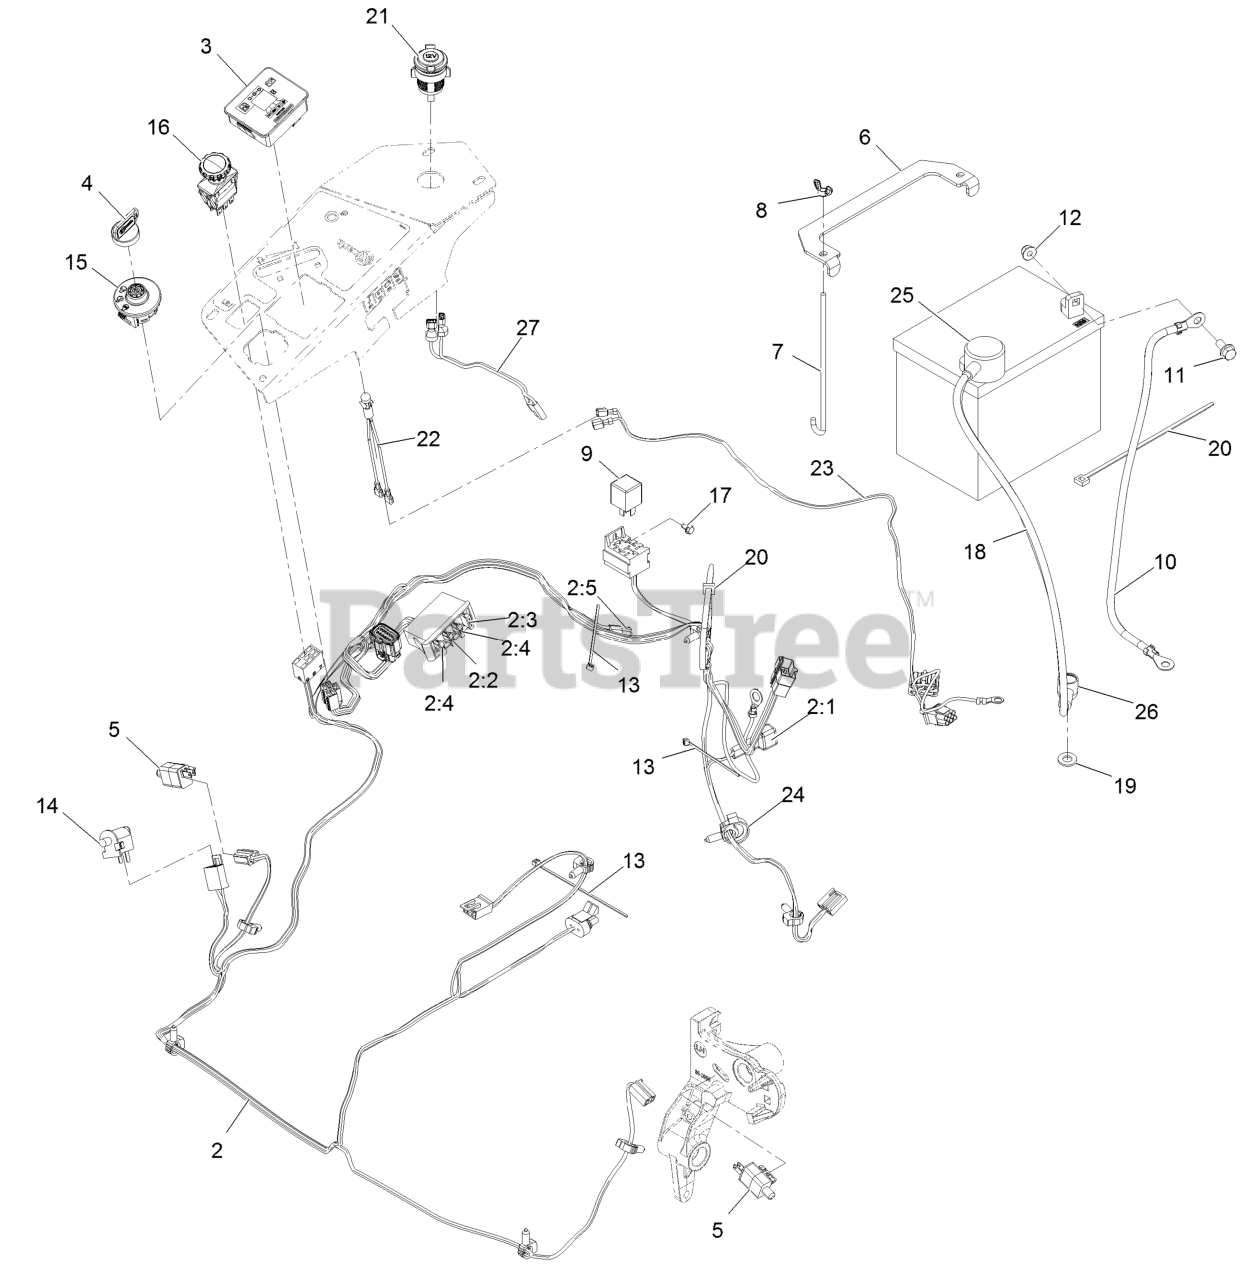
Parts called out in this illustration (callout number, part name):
2	HARNESS-WIRE, MAIN
2:2	FUSE-BLADE, 10 AMP
2:3	FUSE-BLADE, 15 AMP
2:4	FUSE-BLADE, 25 AMP
2:5	CAP-PLUG
3	FUEL/HOUR METER ASM
4	KEYS-IGNITION (SPARE PAIR
4	KEY-IGNITION
6	STRAP-TIE DOWN, BATTERY
7	BOLT-HOLDDOWN
8	WINGNUT
10	CABLE-BATTERY, NEGATIVE
11	SCREW-HHF
12	NUT-HF, NI
13	TIE-CABLE
14	SWITCH-BAIL
16	SWITCH-PTO, 10 AMP
17	SCREW-HWH
18	CABLE-BATTERY, POSITIVE
19	WASHER-FLAT
20	TIE-PLASTIC
21	RECEPTACLE-12V
22	INDICATOR-LED, RED
23	HARNESS-LIGHT, INDICATOR
24	CLAMP-HOSE
25	INSULATOR-BATTERY
26	INSULATOR-SOLENOID
27	HARNESS, RECEPTACLE 12V
